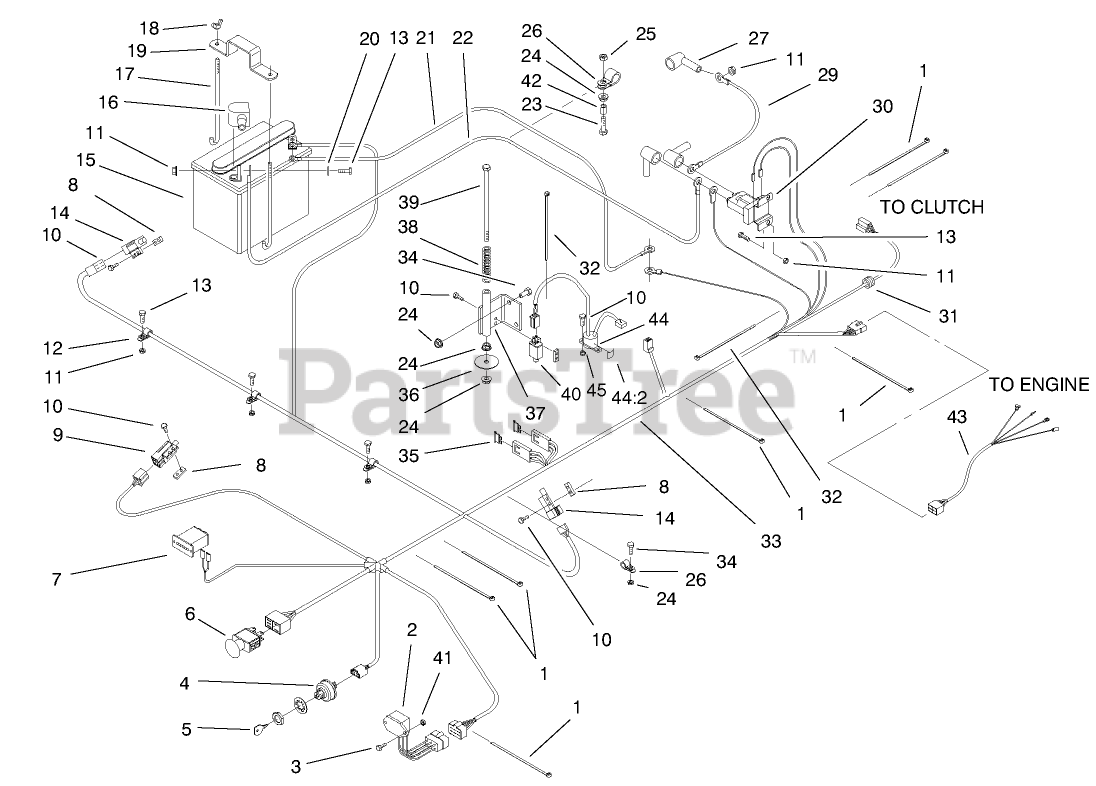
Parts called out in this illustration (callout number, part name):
1	Tie-Plastic
2	Module-Safety
3	Bolt-CARR
4	Ignition Switch
5	KEY-IGNITION
6	Switch
7	Meter-Hour
8	Plate
9	Switch-Brake
10	SCREW-HEAD, PAN
11	NUT-HF
12	Clip
13	SCREW-HH
14	Switch-Drive Lever
15	Battery
16	Insulator Battery
17	Bolt
18	Wingnut
19	Strap-Hold Down
20	WASHER-FLAT
21	Cable-Ground
22	Wire
23	Bolt-TAP
24	NUT-HF
25	Nut-Lock
26	Clip
27	Insulator Solenoid
29	Wire-Starter
30	Switch-Solenoid
31	Grommet
32	Tie-Plastic
33	Harness-Wiring
34	SCREW-HH
35	Fuse
36	Wahser
37	Bracket-Switch, Seat
38	Spring
39	Screw
40	Switch-Seat
41	NUT-LOCK, NI
42	Bushing
43	Harness-Wire
44	Switch-Tilt
44:2	Decal
45	NUT-LOCK, NI
